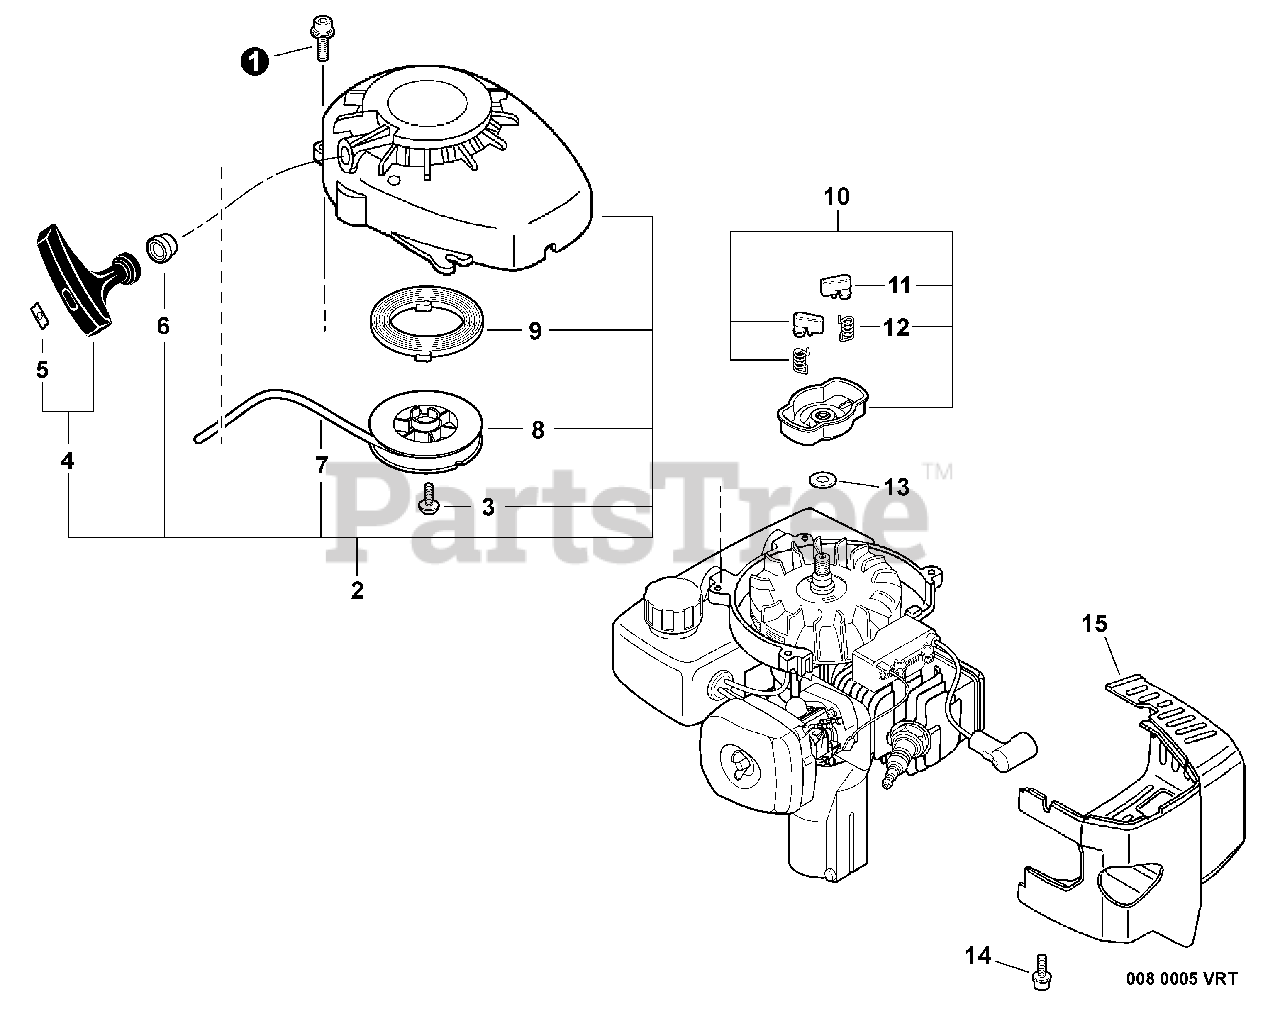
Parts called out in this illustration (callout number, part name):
1	SCREW 4×16
2	STARTER ASSY
3	SCREW
4	GRIP, STARTER
5	RETAINER, ROPE
6	GUIDE, ROPE
7	ROPE, STARTER
8	REEL, ROPE
9	SPRING, RECOIL
10	PAWL ASSY, STARTER
11	PAWL, STARTER - BLACK
12	SPRING, RETURN
13	WASHER, SPRING 8
14	SCREW 4×18
15	COVER, CYLINDER
